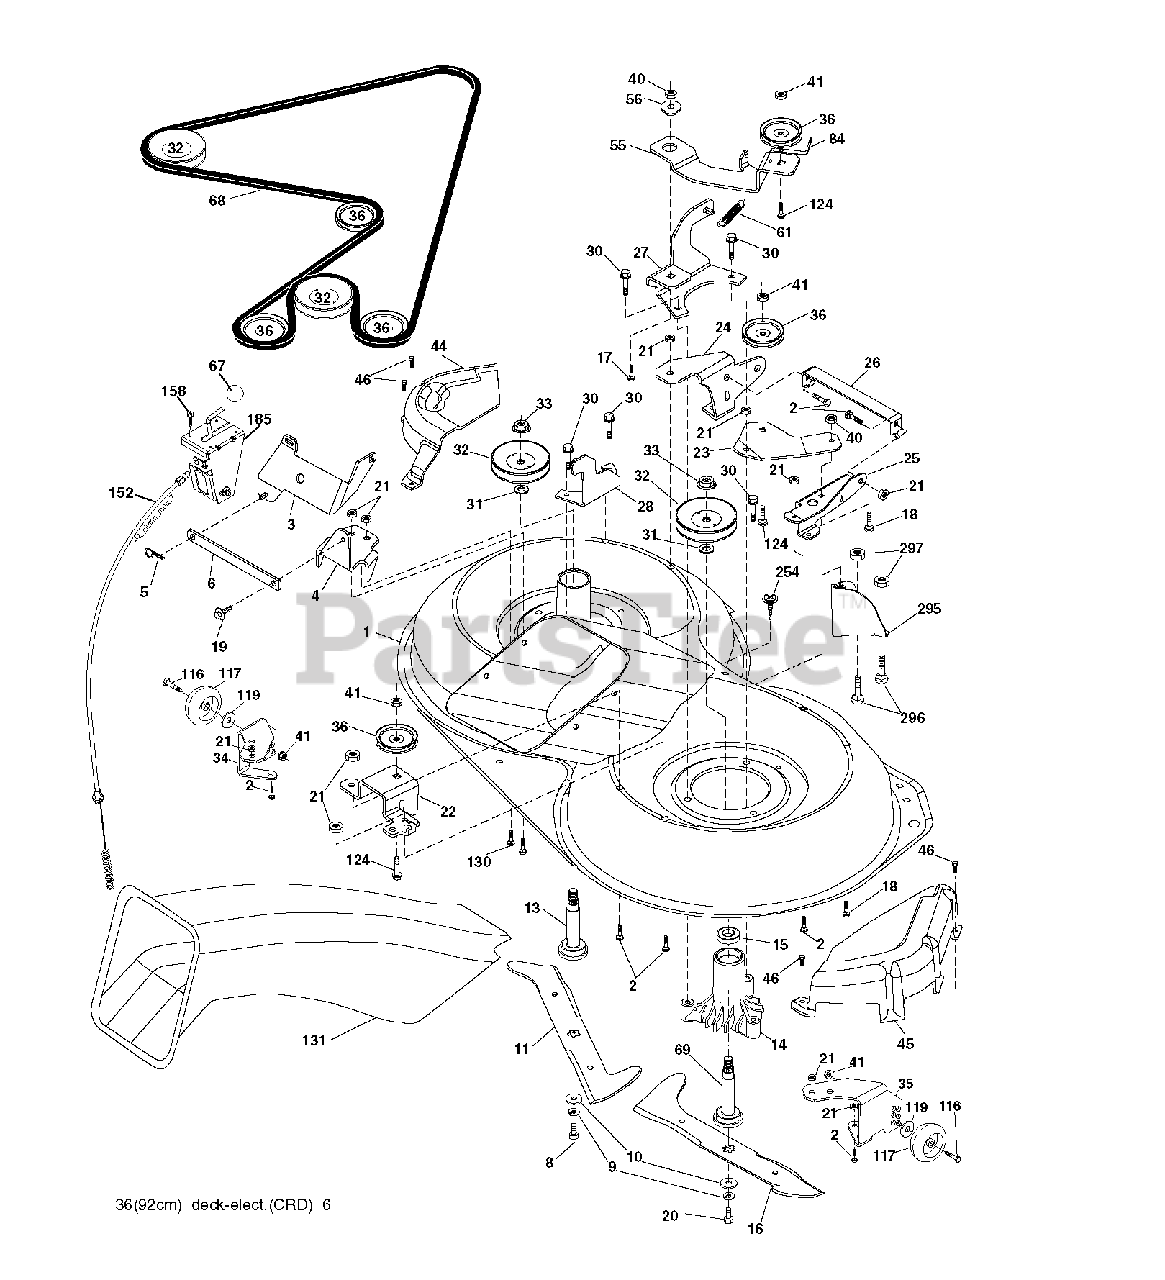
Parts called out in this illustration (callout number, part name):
2	BOLT
3	BRACKET
5	RETAINER-SPRNG RB
6	BAR SWAY
9	LOCKWASHER
10	WASHER.BLADE
13	SHAFT ASM VENT
14	HSG MANDREL
17	BOLT.3/8-14X1.25
19	BOLT SHD 5/16-18
21	LOCKNUT
24	BRACKET
25	BRACKET
28	BRACKET
30	SCREW, WASHER HEAD
31	WASHER.SPACER.MANDREL
32	PULLEY MANDREL
33	NUT.FLANGE.LOCK.TOP
36	PULLEY.IDLER.4.25
40	LOCKNUT
41	NUT LOCK FLG 3/8-16 UNC
45	MANDREL COVER
46	SCREW.1/4-20X5/8
56	SPACER.RETAINER.MOWER
67	KNOB T (3/8 HOLE)
69	SHAFT.ASM.W/LWR.BRG.RH.THREAD
84	KEEPER, BELT IDLER
116	BOLT.SHOULDER.3/8-16X3-5/8
117	WHEEL. GUAGE RALLY
124	BOLT.3/8-16X1.50
131	CHUTE BAGGER
158	SCREW
185	HEAD ASM. CABLE CLUTCH
254	SCREW 3/8-16X1
296	BOLT
297	NUT CENTERLOCK
